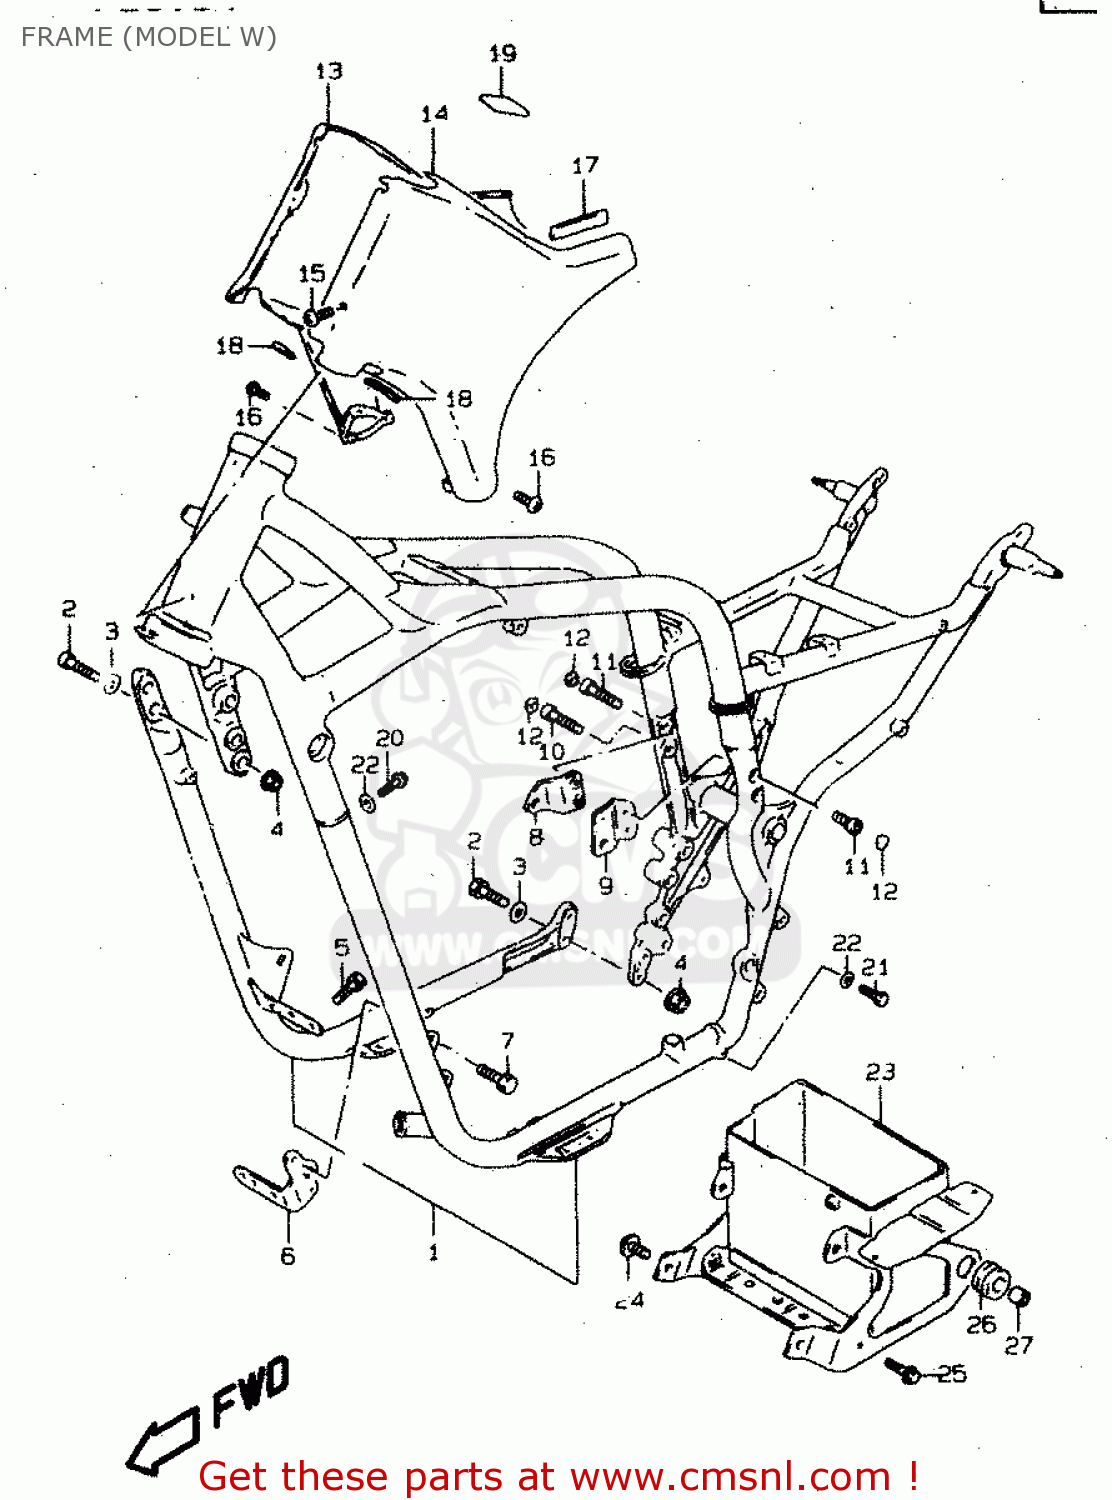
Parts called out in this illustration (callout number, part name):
1	FRAME SET(RED)
2	BOLT(10X33)
3	WASHER
4	NUT
5	BOLT
6	PLATE,ENGINE MOUNT NO.1,L
7	BOLT, UPPER
8	PLATE,ENGINE MOUNT NO.3,R
9	PLATE,ENGINE MOUNT NO.3,L
10	BOLT
11	BOLT(8X30)
12	CAP(OD:14.5)
13	COVER,FRAME HEAD,RIGHT
14	COVER,FRAME HEAD,LEFT
15	SCREW 6X10
16	SCREW
17	PROTECTOR(80X80X2)
18	MOLDING
19	TAPE,FRAME HEAD COVER
20	UNION
21	BOLT
22	GASKET(6.2X11X1).2 (NAS)
23	HOLDER,BATTERY
24	BOLT
25	BOLT
26	CUSHION
27	BUSH
